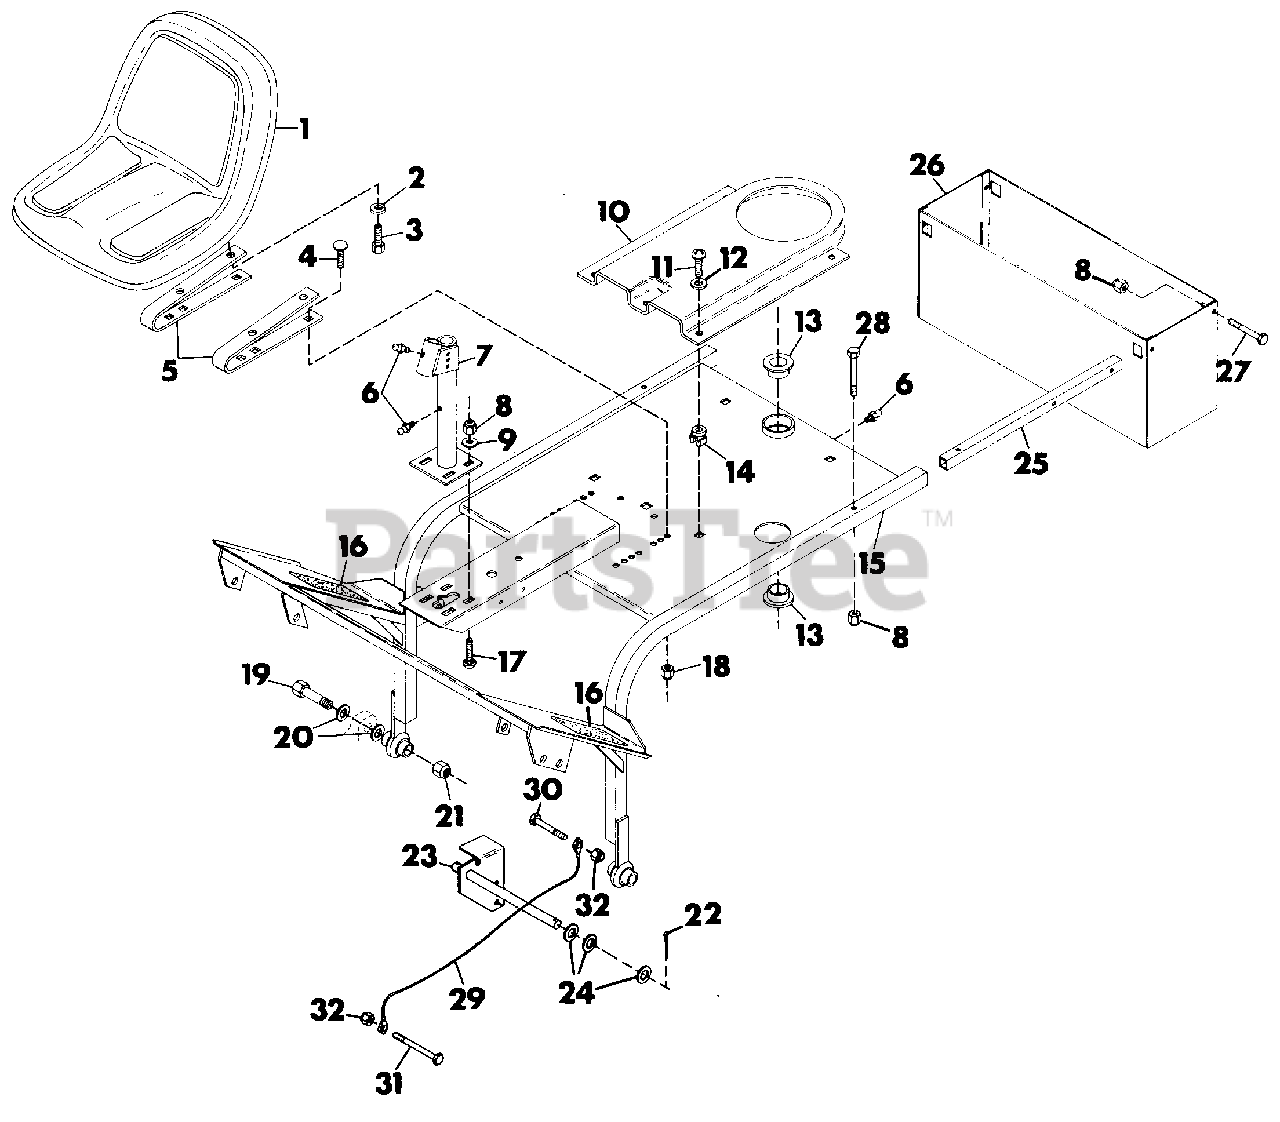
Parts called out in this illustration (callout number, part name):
1	SEAT, HIGH BACK
2	WASHER, LOCK 5/16
3	BOLT, HEX 5/16-18X.75
4	BOLT, CARRIAGE 5/16-18X1.00
5	SPRING, SEAT
6	FITTING, LUBE 1/4-28
7	TUBE, STEERING
8	NUT, LOCK 3/8-16
9	WASHER, FLAT .406X.812X.065
10	COVER, CHAIN
11	SCREW, MACHINE 1/4-20X.625 RD HD
12	WASHER, FLAT .281X.625X.065
13	BEARING, FLANGED
14	GROMMET, PLASTIC
15	WELDMENT, FRAME OFC
16	COVER, LARGE FOOTBOARD
17	BOLT, 3/8-16X1.00 RD HD SQ NK
18	NUT, LOCK 5/16-18
19	BOLT, HEX 3/4-10X3.75
20	WASHER, FLAT .812X1.469X.130
21	NUT, LOCK 3/4-10
22	PIN, COTTER .125X1.25
23	WELDMENT, LIFT BRACKET
24	WASHER, FLAT .656X1.250X.100
25	TUBE, SUPPORT
26	WELDMENT, WEIGHT BOX
27	BOLT, HEX 3/8-16X2.25
28	BOLT, HEX 3/8-16X2.75
29	CABLE, STOP
30	BOLT, HEX 5/16-24X2.25
31	BOLT, HEX 5/16-24X3.50
32	NUT, LOCK 5/16-24
NS	DECAL, PRO MASTER-60
NS	DECAL, GRAVELY LOGO
NS	DECAL, AMERICA
